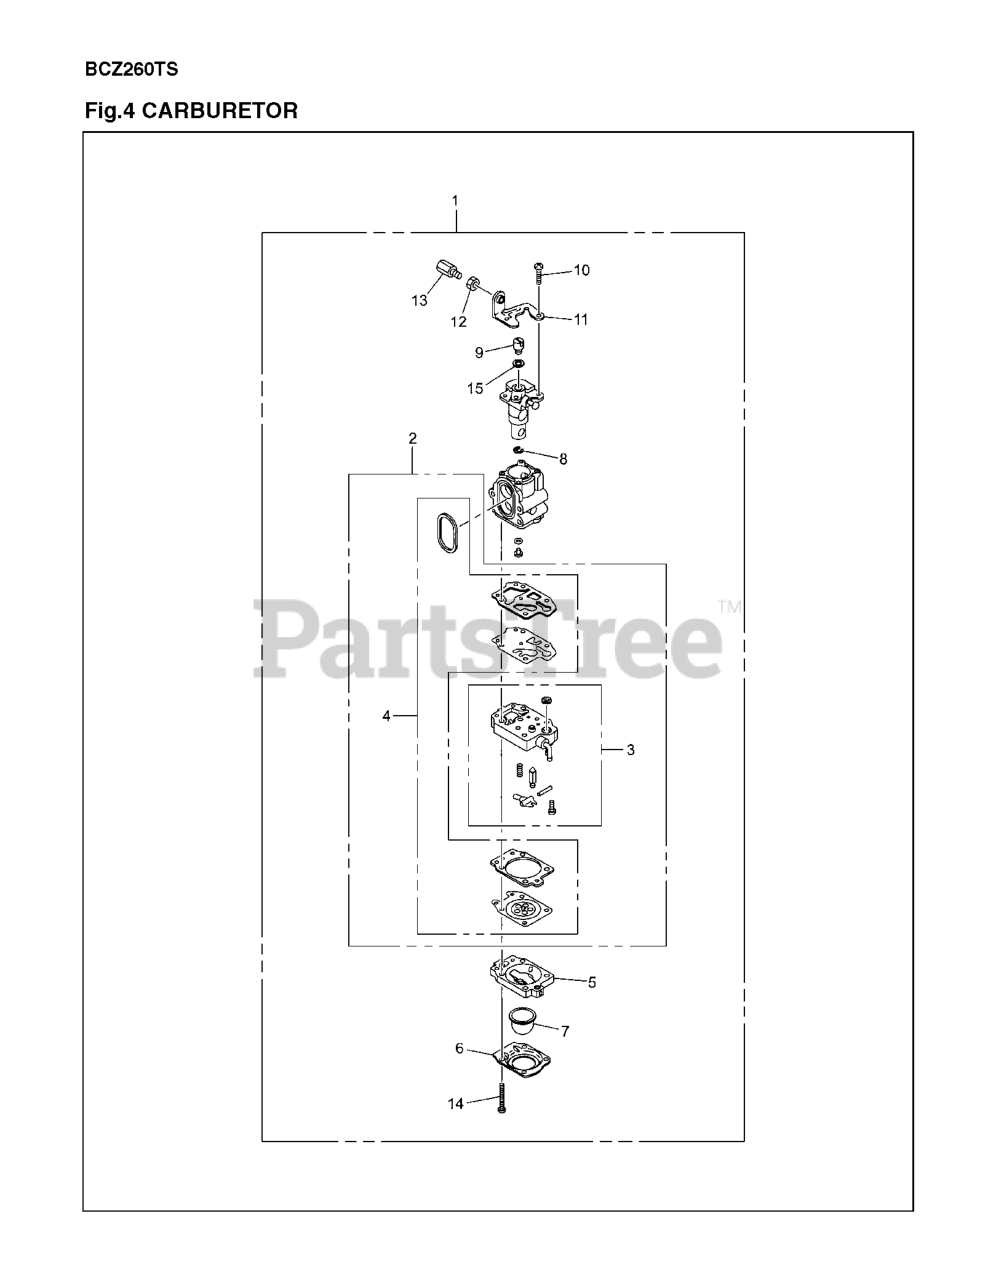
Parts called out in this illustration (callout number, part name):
1	CARBURETOR ASSY
2	REBUILD KIT
3	CARBURETOR BODY
4	GASKET KIT
6	1OVER
8	RING
9	SWIVEL
10	SCREW
11	BRACKET
12	NUT
13	ADJUSTER
15	WASHER
